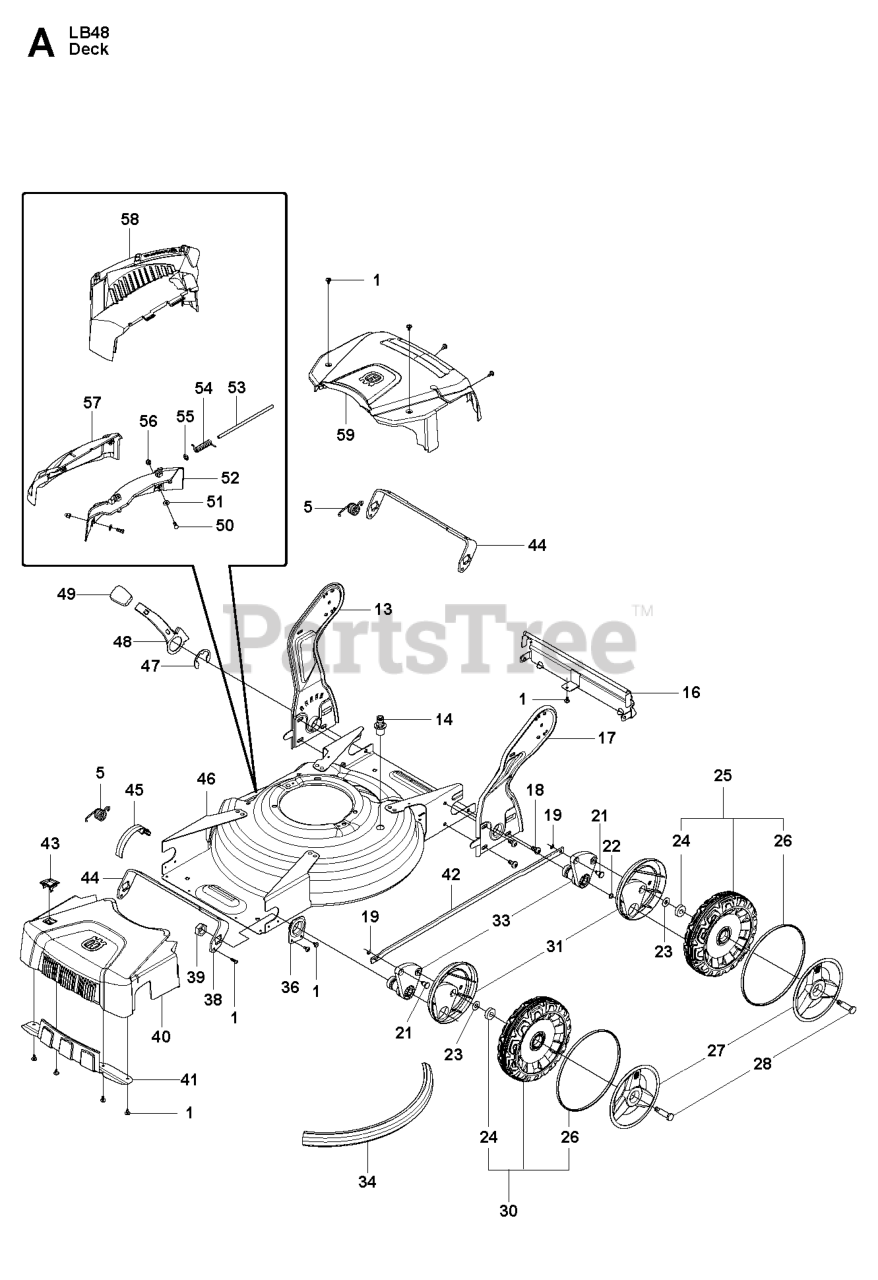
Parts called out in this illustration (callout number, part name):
1	SCREW ITXPANTT M5X10 ZPB (A00
19	FASTENER
24	BALL BEARING
46	CHASSIS 48S A009 PAINTED
59	REAR COVER A009-2
